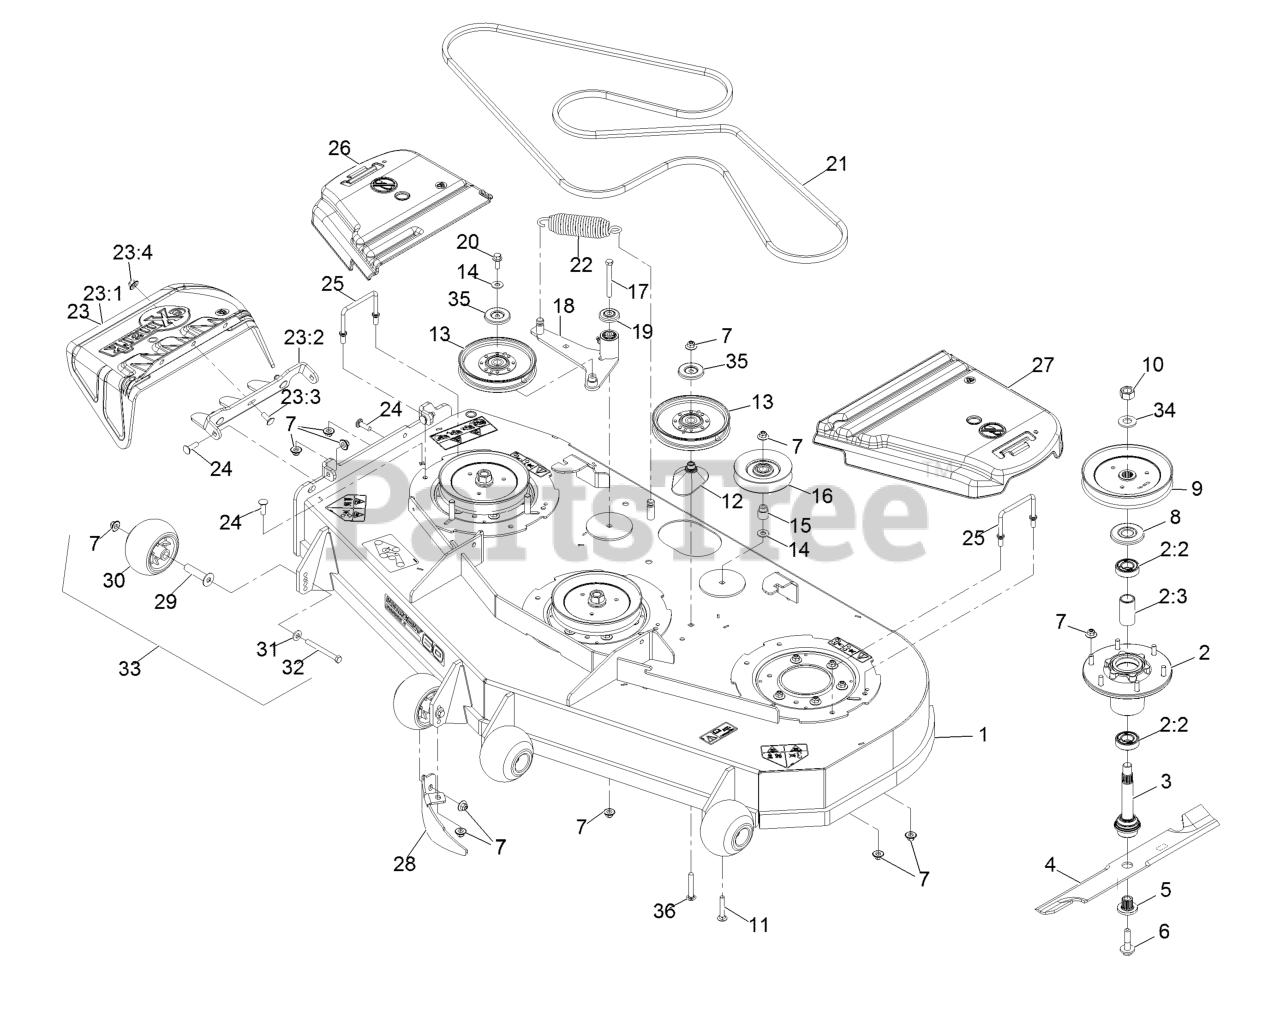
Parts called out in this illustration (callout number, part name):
1	Deck ASM-604
2	ASM-Cutter Hsg With Bearings
2:2	Bearing-Ball
2:3	Spacer-Bearing
3	ASM-Spindle And Seal
4	Blade, Solid
4	Blade-Extreme 2, 20.50"
4	Blade, Notched
4	Blade, Mulching
4	Blade, Low Lift
5	Bushing, Splined
6	Screw,Sems (1/2-20 X 2.19, GR5)
7	Nut-Flange, NI
8	Guard,Bearing Top .989
9	Sheave,Blade Drive 7.25
10	Nut-Hex
11	Screw-CARR
12	Spacer-Pulley
13	Idler-Pulley
14	Washer-Flat
15	Bushing, Idler
16	Pulley-Idler
17	Screw-HH
18	Deck Idler ASM
19	Guard-Top
20	Screw-HHF
21	V-Belt
22	Spring-Extension
23	ASM,Discharge Chute
23:1	Chute, Discharge
23:2	Bracket,Discharge Chute
23:3	Screw-CARR
23:4	Nut-Flange, NI
24	Screw-CARR
25	Wireform-Cover
26	Cover-Belt, RH
27	Cover-Belt, LH
28	Dogleg - Lz60
29	Axle, Roller
30	Roller-Anti-Scalp
31	Washer-Belleville
32	Screw-HH
33	Kit, Anti-Scalp Roller
35	Shield-Dust
36	Screw-CARR
